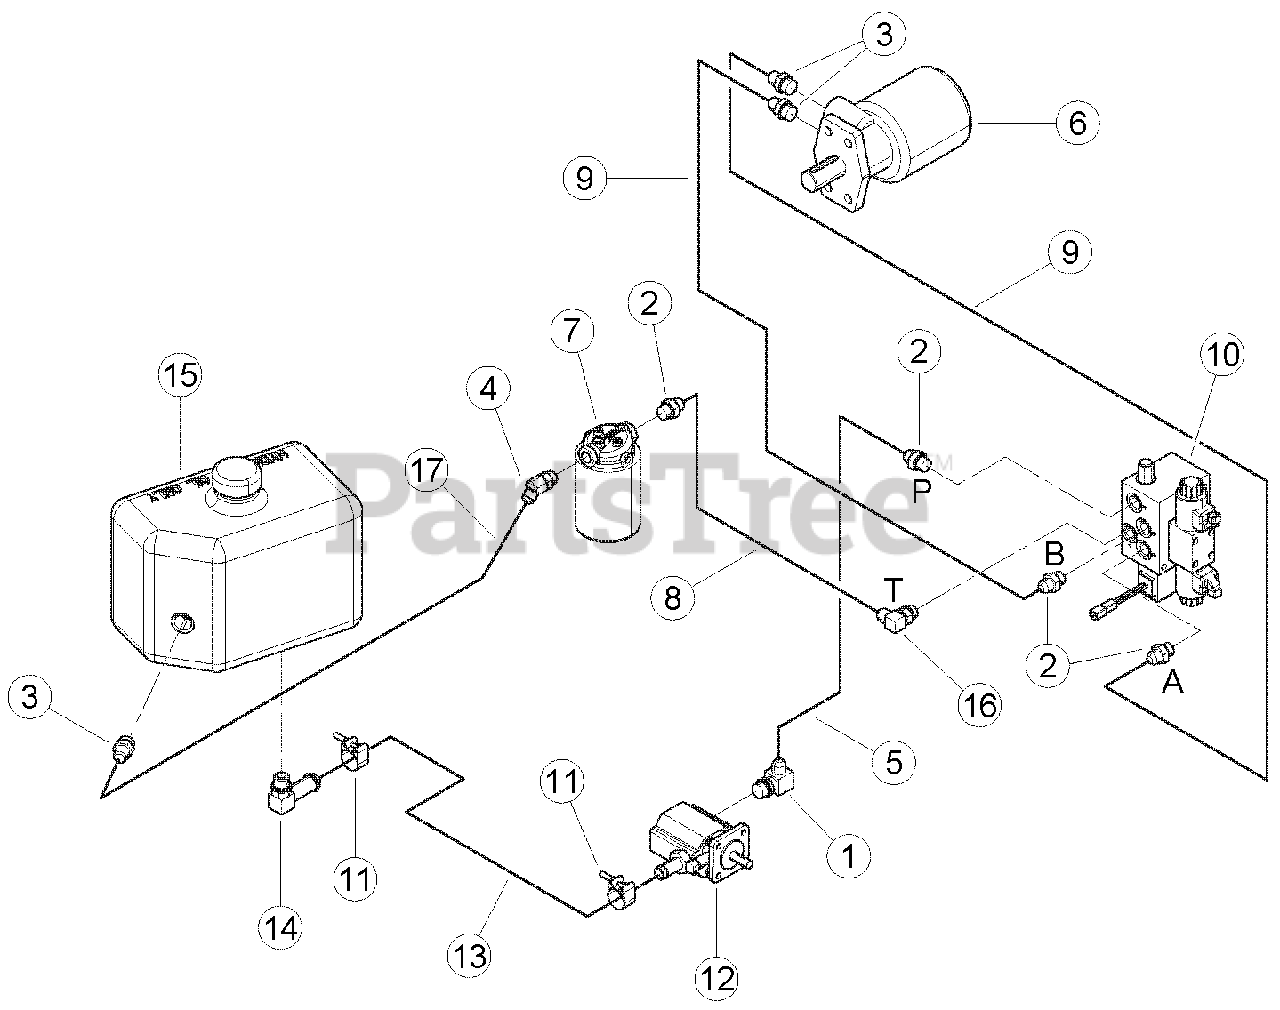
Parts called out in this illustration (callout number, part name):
1	ADAPTER, -10 MORING / -8 MJIC 90 DEG.
2	ADAPTER, -8 MORING / -8 MJIC
3	ADAPTER, -10 MORING / -8 MJIC
4	ADAPTER, -8 MORB / -8 MJIC 45 DEG.
5	HOSE ASSY', -8 FMJIC / -8 FMJICSW X 8-1/2
6	MOTOR, 45 CU. IN. HYDRAULIC
7	FILTER, SPIN ON
8	HOSE ASSY', -8 FMJIC / -8 FMJIC 90 X 21 IN.
9	HOSE ASSY', -8 FMJIC / -8 FMJIC 90 X 61 IN.
10	ASSEMBLY, CHIPPER FLOW VALVE
11	CLAMP, 1" OD. HOSE T-BOLT
12	PUMP, 2 STAGE CW HI/LO 0.605 DISP.
13	HOSE, .75 ID X 28 IN 100R4 HYD
14	ADAPTER, -10 MORING/.75 90 DEG. HOSE
15	TANK, OIL RESERVOIR
16	ADAPTER, -8 MORING / -8 MJIC 90 DEG.
17	HOSE, 3/8 X 35 -8 FJICSW
